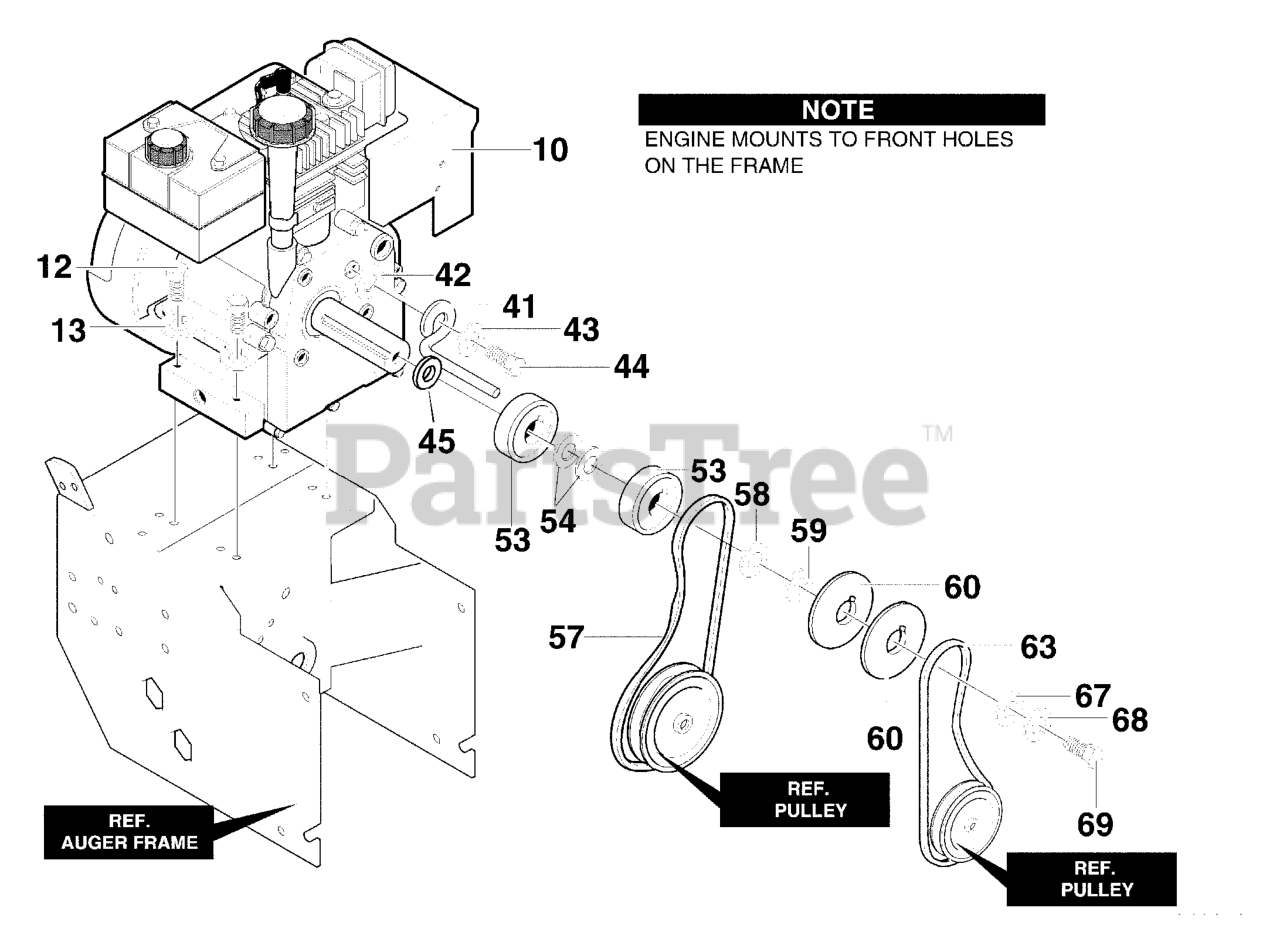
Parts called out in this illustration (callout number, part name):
10	10HP ENGINE
12	SCREW, 5/16-18
13	WASHER, SPTLK .31X.58X.08
41	GUIDE, ROD BELT
42	PLASTIC WASHER
43	WASHER, SPTLK .31X.58X.08
44	SCREW, 5/16-24 x 1.00
53	PULLEY, HALF
54	WASHER, FLAT .752X.91X.02
57	BELT, V 3L 33.13LG
58	FLATWASHER .765X1.12X.06
59	SPACER, SLEEVE
60	PULLEY, ENGINE
63	BELT, V 4L38.1LG
67	WASHER, FLAT .375X1.25X.104
68	WASHER,HVSPTLK .38ID
69	SCREW, 3/8-24 x 1.00
